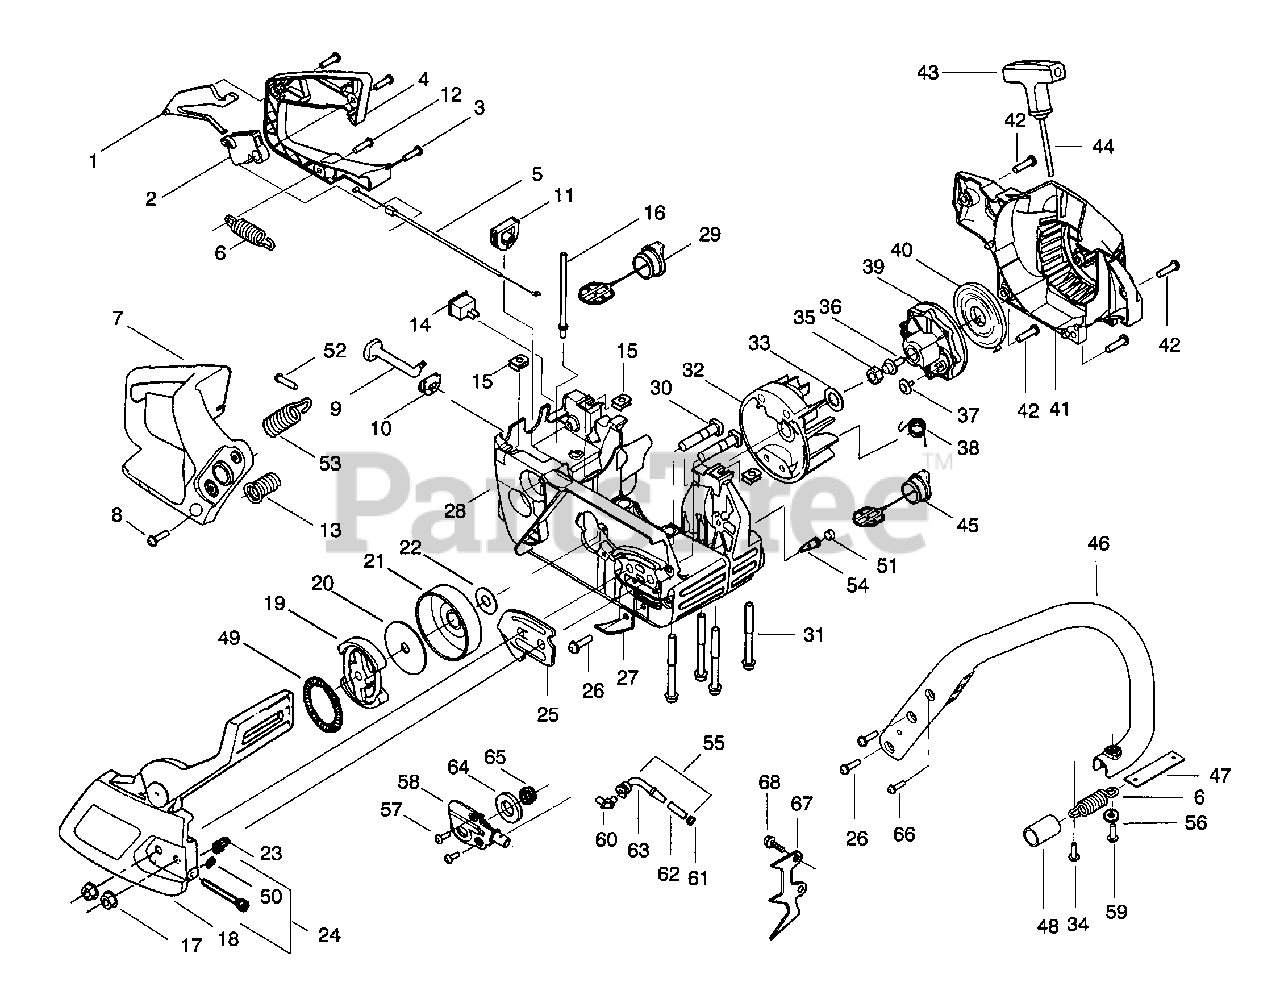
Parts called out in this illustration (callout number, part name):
1	THROTTLE LOCK
2	THROTTLE TRIGGER
3	SCREW,FRONT HBAR 36/41
5	THROTTLE WIRE
6	SPRING
8	SCREW
12	SCREW-10-14 X 13/16 (PL
13	SPRING
18	COVER
19	CLUTCH ASSEMBLY
20	FRICTION DISC,CLUTCH 36/41
21	CLUTCH DRUM ASSY
22	DUST COVER 36/41
23	ADJUST PIN,BAR 36/41
27	CHAIN CATCHER 36/41
28	CRANKCASE
29	TANK CAP
32	FLYWHEEL ASS'Y
33	WASHER-FLYWHEEL
35	NUT-FLYWHEEL
38	SPRING STR DOG
39	STARTER PULLEY
41	STARTER HOUSING
42	SCREW,STRTR CVR 36/41
43	HANDLE
45	OIL TANK CAP
46	HANDLE
47	STRAP
49	CLUTCH SPRING 36/41
51	BRONZE PLUG
53	SPRING
54	VALVE-CHECK (DUCKBILL)
61	PLUG
62	FILTER
63	PICK-UP OILER
65	WORM GEAR
67	SPIKE
68	SCREW,FRONT HBAR 36/41
